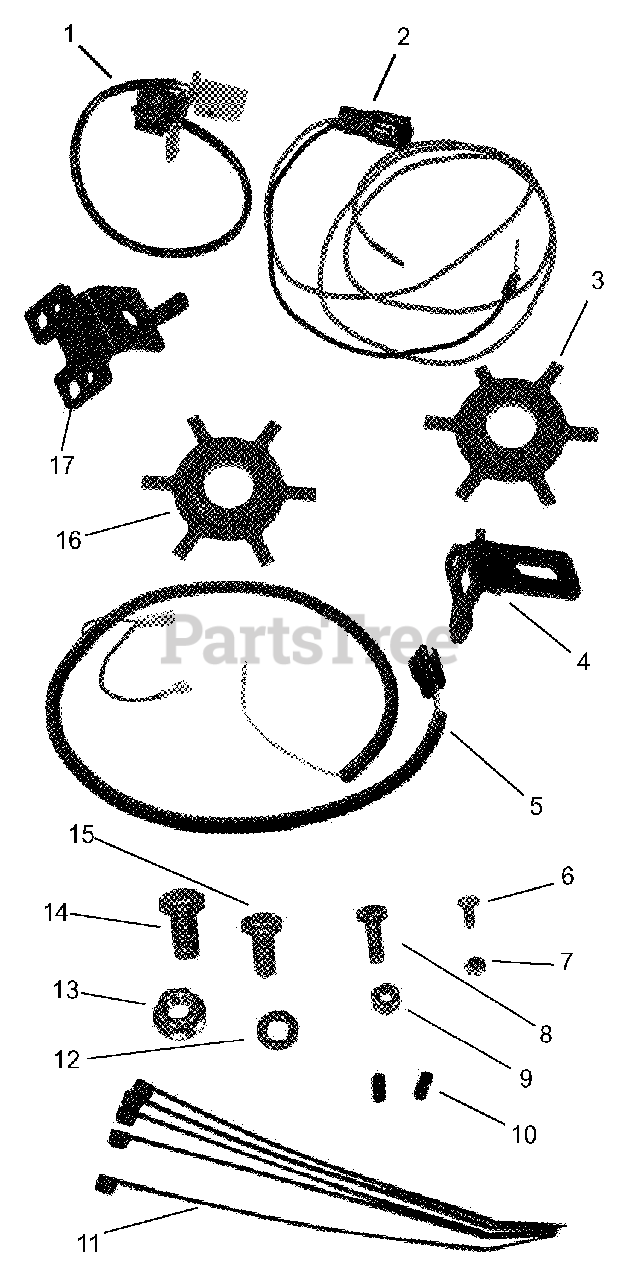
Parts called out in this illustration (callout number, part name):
1	SENSOR, EYE-Q ENGINE RPM
2	HARNESS, DIESEL RPM SENSOR
3	SPROCKET, RPM 6T 1.76ID
4	BRKT, RPM SENSOR MTG.
5	HARNESS,RPM SENSOR VERT&L/CAIR
6	BLT-HEX M4X0.7X12MM YZ
7	@NUT-LK-NYL M4-0.7 YWZC
8	@BLT-HEX M6-1X16 YWZC
9	NUT-LK-NYL M6-1 YWZC
10	SCR-SET 10-24X.38 UNC-3A
11	CABLE TIE LG 5-1/2
12	@WSHR-LK .31X.078 REG YWZC
13	@NUT-LK-TOP-FLG .38-16 YWZC
14	@BLT-HEX .38-16X.75 GR5 YWZC
15	BLT-HEX M8 X 1.25X16 YWZC
16	SPROCKET, RPM 6T 1.65ID
17	BRACKET, RPM SENSOR MTG.L/CAIR
